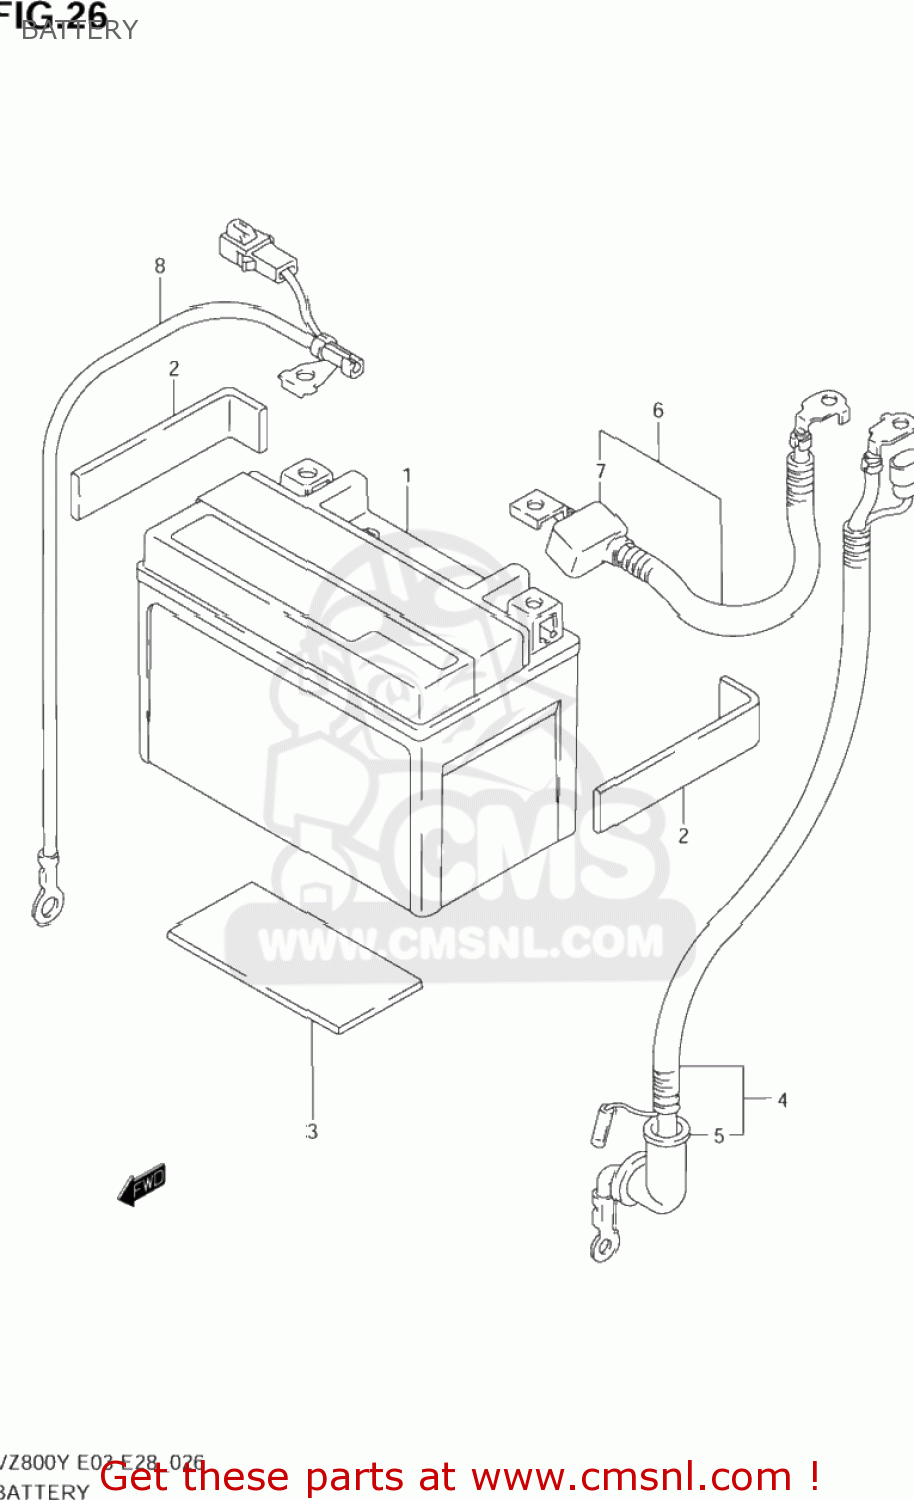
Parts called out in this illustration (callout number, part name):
1	BATTERY ASSEMBLY (12V) FTX
2	PROTECTOR(170X95X3.0)
3	PROTECTOR(170X95X3.0)
4	WIRE,STARTER MOTOR LEAD
5	CAP,STARTER MOTOR LEAD
6	WIRE,BATTERY PLUS LEAD
7	CAP,BATTERY PLUS
8	WIRE,BATTERY MINUS
